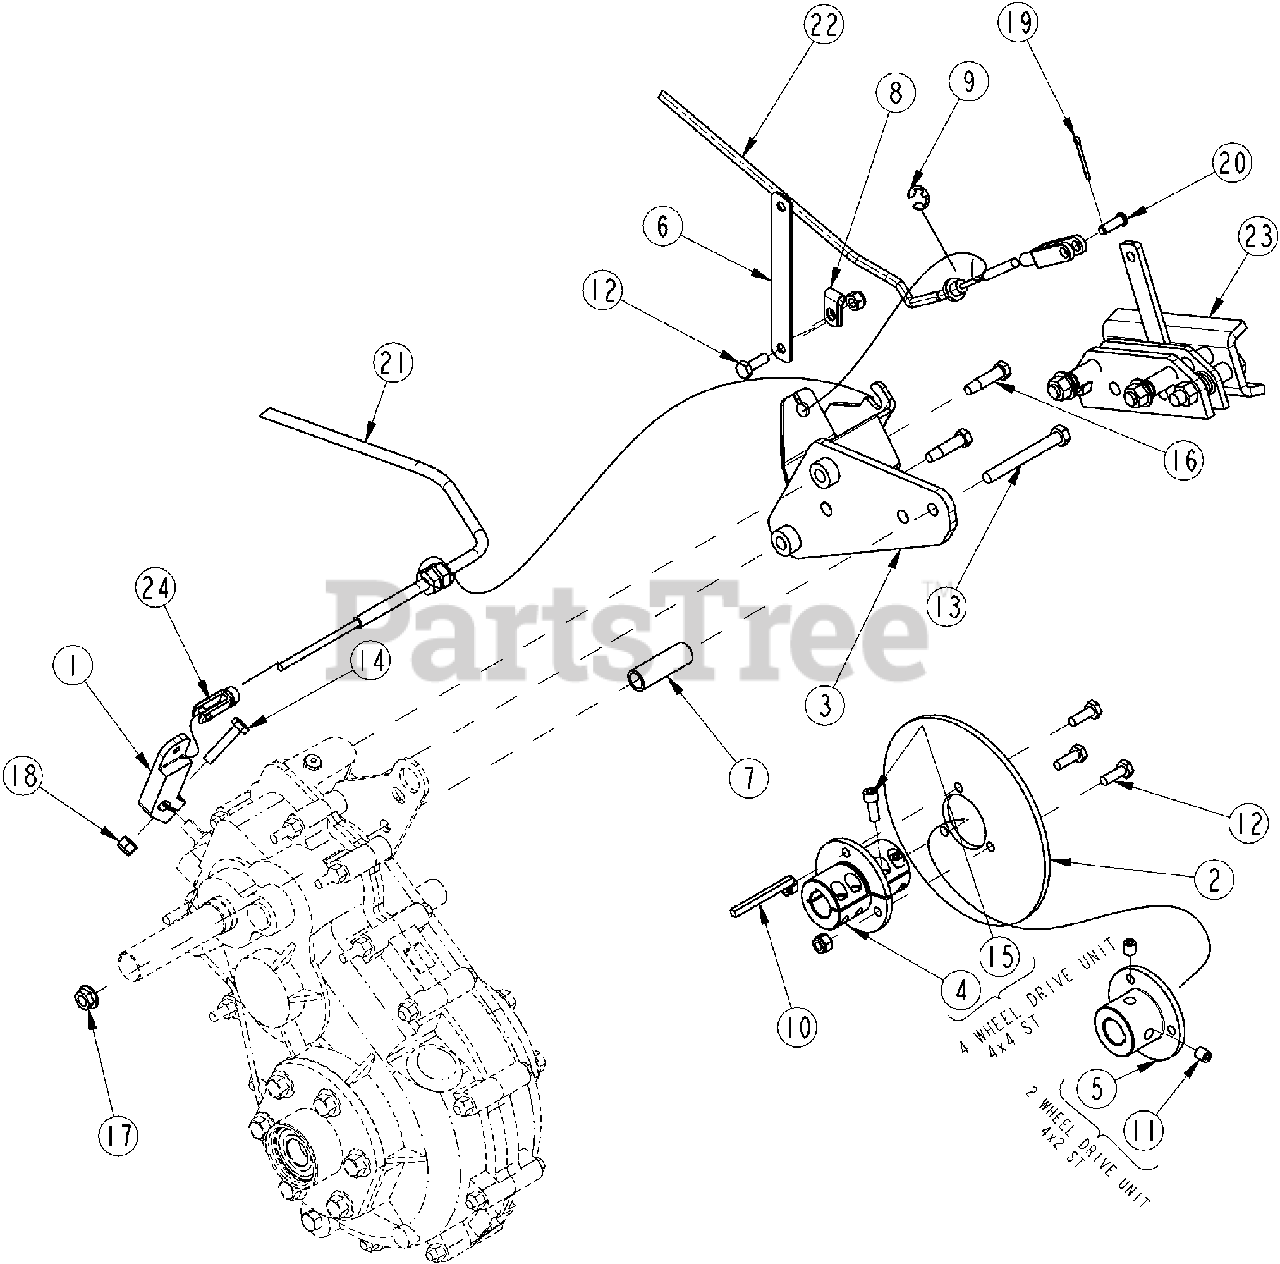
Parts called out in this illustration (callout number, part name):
1	SHIFT LEVER
2	BRAKE DISC
3	CALIPER MOUNT BRACKET
4	CLAMP COUPLING
5	BRAKE HUB ADAPTER
6	BRAKE CABLE CLIP PLATE
7	CALIPER SPACER TUBE
8	WIRING/TUBE CLIP FOR 1/4 OD
9	E RETAINING RING EXTERNAL
10	KEY .187 X .187 X 2.25 LG
11	SCREW SET 5/16-18 SKT KP X 3/8
12	HHCS 1/4-20X3/4 GR5
13	HHCS 5/16-18X2 3/4 GR5
14	HHCS 1/4-20X1 1/4 GR8
15	HSHCS 1/4-28X5/8
16	HWH 5/16-18X1 1/4 THREAD-ROLL
17	NUT HEX FLG TOP LK 5/16-18 YLW
18	NUT HEX NYLOCK 1/4-20
19	PIN COTTER 3/32 X 1 LONG
20	PIN CLEVIS 1/4 X 3/4
21	SHIFT CABLE (DASH)
22	PARK BRAKE CABLE 105.00" LG
23	BRAKE CALIPER
24	YOKE 10-32 W/ LOCK
